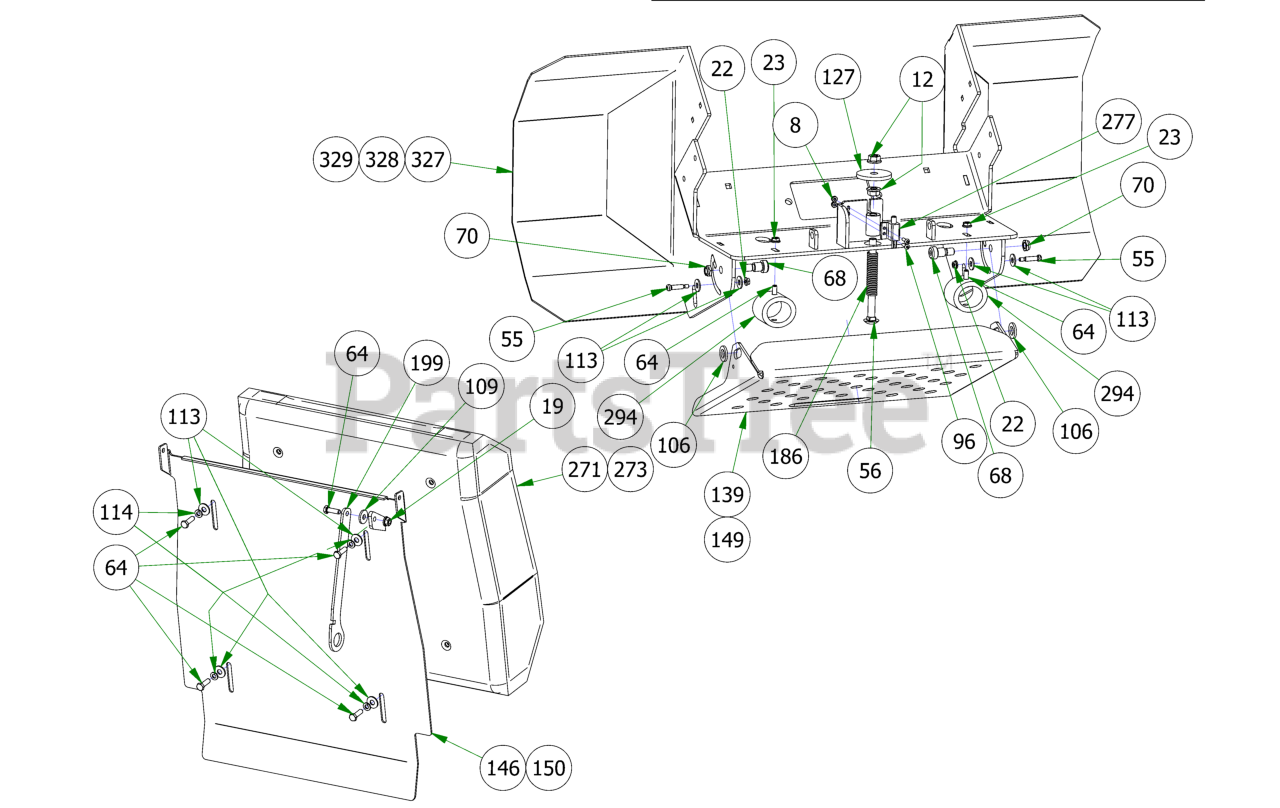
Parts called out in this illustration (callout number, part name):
4	3326 Wellnut (1/4-20 x 5/18")
8	10-24 NYLON INSERT LOCKNUT ZINC
11	3/8-16 NYLON INSERT FLANGE LOCKNUT (GR.F) ZINC
12	1/2-13 HEX SERRATED FLANGE NUT HARD/ZINC
19	5/16-18 NYLON INSERT FLANGE LOCKNUT ZINC
21	1/4-20 NYLON INSERT LOCKNUT ZINC
22	1/4-20 HEX SERRATED FLANGE NUT HARD/ZINC
23	5/16-18 HEX SERRATED FLANGE NUT HARD/ZINC
55	Steel Shoulder Screw 1/4"-20 x 7/8" Diameter 5/16"
56	1⁄2-13 x 6 Carriage Bolt, 2” min threads, Grade 2
64	5/16-18 X 1 HEX CAP SCREW (GR.5) ZINC
67	3/8-16 X 2 HEX CAP SCREW (GR.5) ZINC
68	5/8 X 5/8 SOCKET SHOULDER BOLT ZINC YELLOW
70	1/2-13 NYLON INSERT JAM LOCKNUT ZINC
73	5/16-18 X 1-1/4 CARRIAGE BOLT ZINC
77	3/8-16 X 1-1/4 HEX CAP SCREW (GR.5) ZINC
78	3/8-16 X 1-1/4 CARRIAGE BOLT ZINC
95	1/4-20 X 3/4 HEX CAP SCREW (GR.5) ZINC
96	10-24 X 3/4 BUTTON SOCKET CAP SCREW 18-8 STAINLESS STEEL
99	.390 ID X .750 OD X .062 THK FLAT WASHER NYLON
106	.635 ID X 1.120 OD X .140 THICK FLAT WASHER NYLON
109	.360 ID X .983 OD X .120 THICK FLAT WASHER NYLON
113	5/16 USS FLAT WASHER (7/8 OD) ZINC
114	5/16 SPLIT LOCKWASHER ZINC
127	MZ Deck Idler Spacer
139	2019 Stand On Platform Plate
140	2019 Stand On Access Panel Plate Black Part
146	Pad Plate Weldment
148	2020 36" Hydrotank Carrier Plate 2020 36" Stand On
149	2020 36" Revolt Platform Plate-Powdercoated
150	36" Pad Plate Weldment 2020 36" Stand On
186	Rider Presence Spring 9657K145
199	Operator Pad Kickstand
256	Hydro Tank Assembly
266	2020 36" Stand On Frame
271	2022 Stand-On Revolt Platform Pad
273	2022 36" Revolt Seat Pad
277	safety Switch
294	GBR-647 Miner Elastomer
297	Grip Tape for 026-0062-00
298	Grip Tape for 026-0158-00
301	EPA Build Date Punch Label
309	2022 Powered By Vanguard Decal
310	2022 Powered By Kawasaki Decal
315	2019 Revolt 726cc Decal Set
316	2019 Revolt Pump Belt Route Decal
317	2019 Revolt Fender Decal - Pair
319	810cc Revolt EFI Fender Decal
320	852cc Revolt EFI Fender Decal
323	36" Revolt Deck Belt Route Decal
327	2020 61" Stand On Platform Support Welded Assembly
328	2020 36" Stand On Platform Support Welded Assembly
329	2019 48"-54" Stand On Platform Support Welded Assembly
